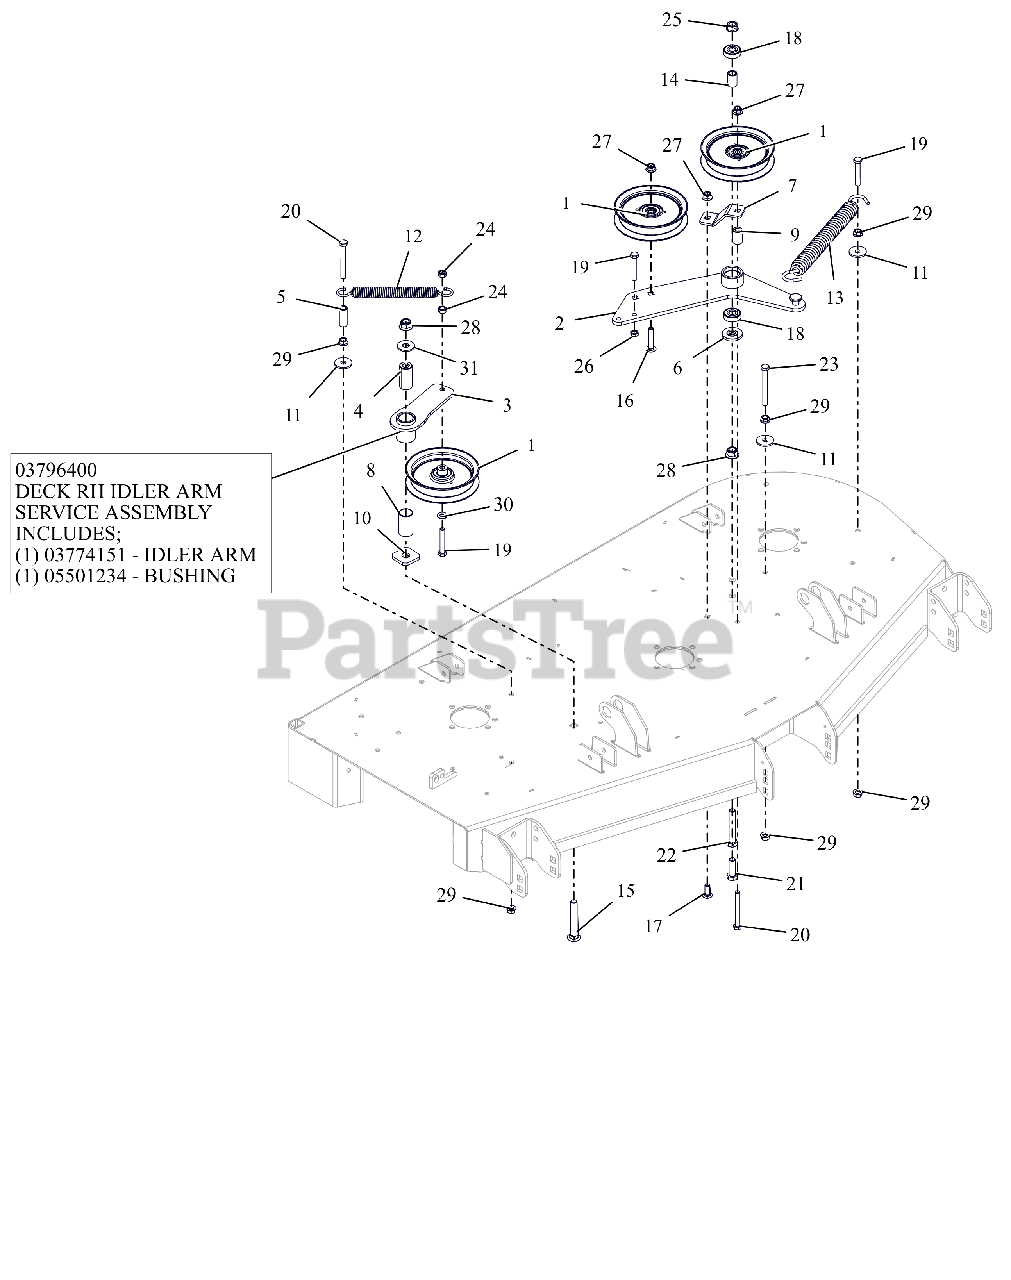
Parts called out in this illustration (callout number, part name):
1	IDLER, FLAT 5.00"
2	DECK PTO IDLER ARM WLDMT - BLK
3	WMT, IDLER ARM - BLACK
3	ASM, IDLER ARM (DECK)
3	BSHG, 1.00X1.125X1.937
4	BSHG, SPCR .502X.997X2.03 PM
5	SPACER, .375IDX.625ODX1.66 PM
6	SPACER, IDLER ARM
7	PTO FIXED IDLER MTG BRKT-ORG
8	BSHG, 1.00X1.125X1.937
9	BUSHING, SLV .380X.750X1.190
10	WSHR-FLT .640X1.75X.250
11	WSHR-FL-STL .406X1.375X.135 YZ
12	SPRING, EXTENSION
13	SPRING, EXTENSION
14	SPACER .510 X .75 X 1.1485
15	@BLT-RDHDSQNK .50-13X3.50 G5YZ
16	BLT-RDHDSQNK .38-16X2.00 SHTYW
17	@BLT-RDHDSHSQNK.38-16X1.0 G5YZ
18	BRG-BALL .500X1.38X.437
19	@BLT-HEX .38-16X2.25 GR5 YWZC
20	@BLT-HEX .38-16X3.25 GR5 YWZC
21	@BLT-HEX .50-13X1.50 GR5 YWZC
22	@BLT-HEX .50-13X3.00 GR5 YWZC
23	@BLT-HEX .38-16X3.50 GR5 YWZC
24	@NUT-LK-CTR .38-16 YWZC
25	NUT-LK-CTR-FLG .50-13 YWZC
26	NUT-HEX-JAM .375-16 YWZC
27	@NUT-LK-NYL-FLG .38-16 YWZC
28	@NUT-LK-NYL-FLG .50-13 YWZC
29	@NUT-SPNLK-FLG .375-16 YWZC
30	@WSHR-FL-STL.406X.812X.065 YWZ
31	@WSHR-FL-STL.563X1.38X.109YWZC
